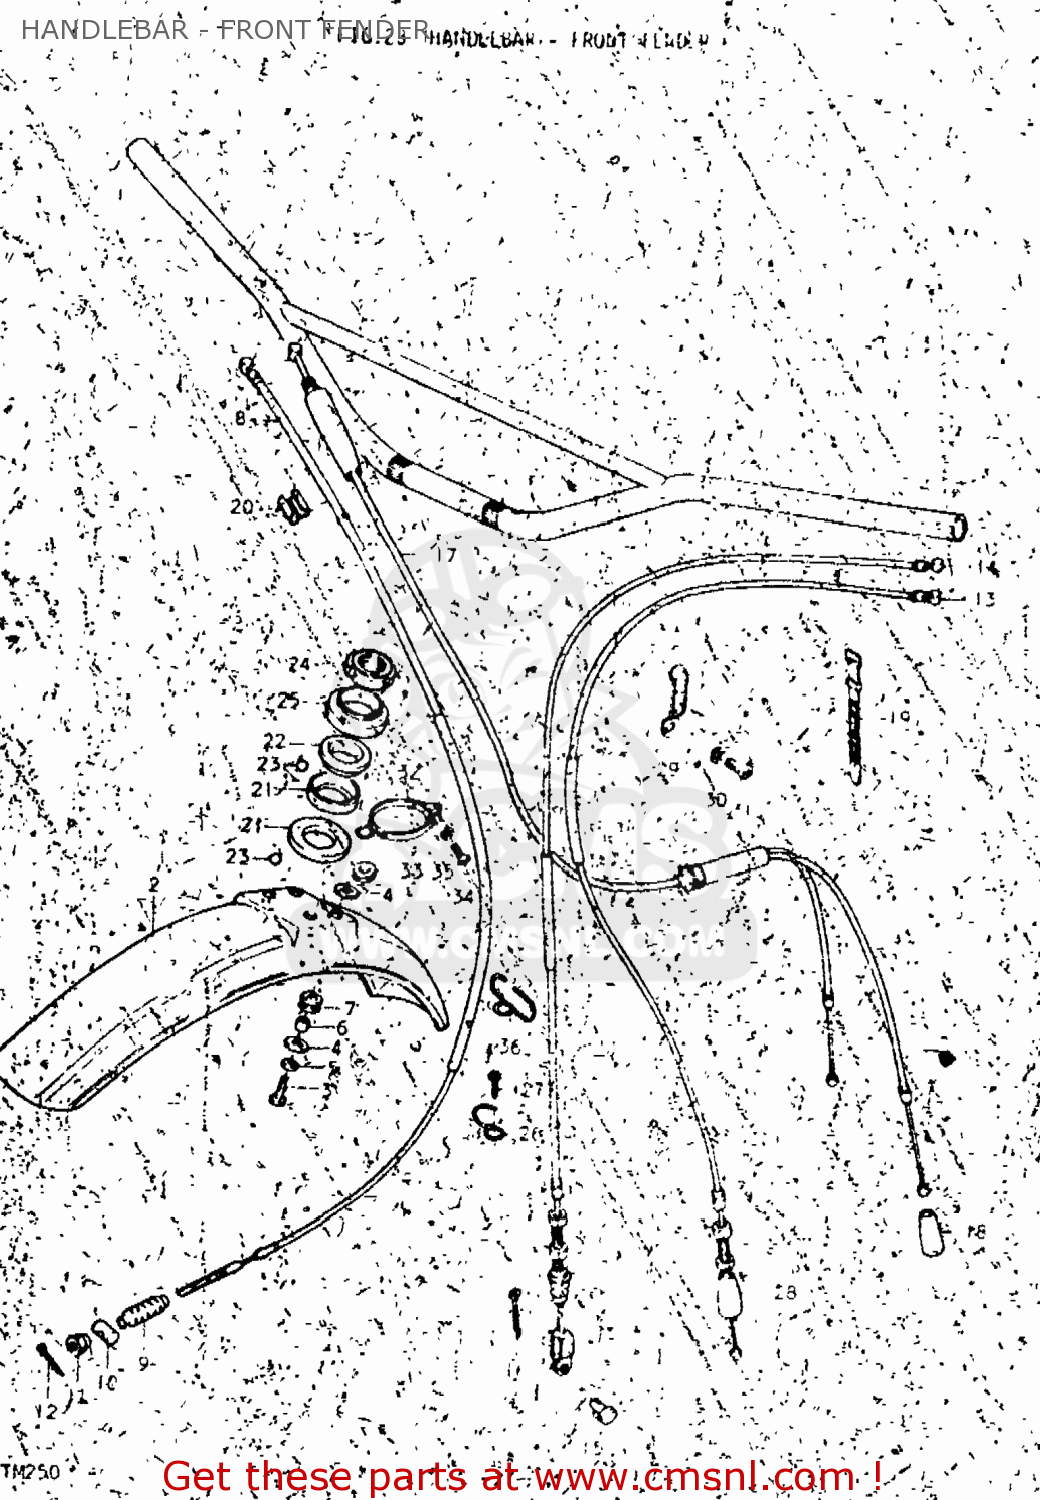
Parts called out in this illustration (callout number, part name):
1	HANDLEBAR
2	FENDER,FRONT
3	BOLT
4	WASHER (6.5X24X1.2)
5	LOCK WASHER
6	SPACER (6.5X10.5X13.5)
7	CUSHION
8	CABLE ASSEMBLY,FRONT BRAKE
9	SEAL,DUST
10	PIN
11	NUT
12	PIN
13	CABLE ASSEMBLY,CLUTCH
14	CABLE ASSEMBLY,CLUTCH
15	PIN(L:15)
16	PIN
17	CABLE ASSEMBLY,THROTTLE
18	DUST SEAL
19	CLAMP
20	CLIP
21	LACE,STEERING INNER LWR
22	LACE,STEERING OUTER UPR
23	BALL
24	NUT,STEERING STEM(25X44X10)
25	DUST SEAL,STEERING UPR
26	GUIDE,CABLE
27	SCREW
28	SEAL,DUST(10X17X45)
29	CLAMP
30	LOCK WASHER
31	SCREW
32	GUIDE,CABLE
33	CUSHION
34	SCREW
35	WASHER
36	GUIDE,CABLE
